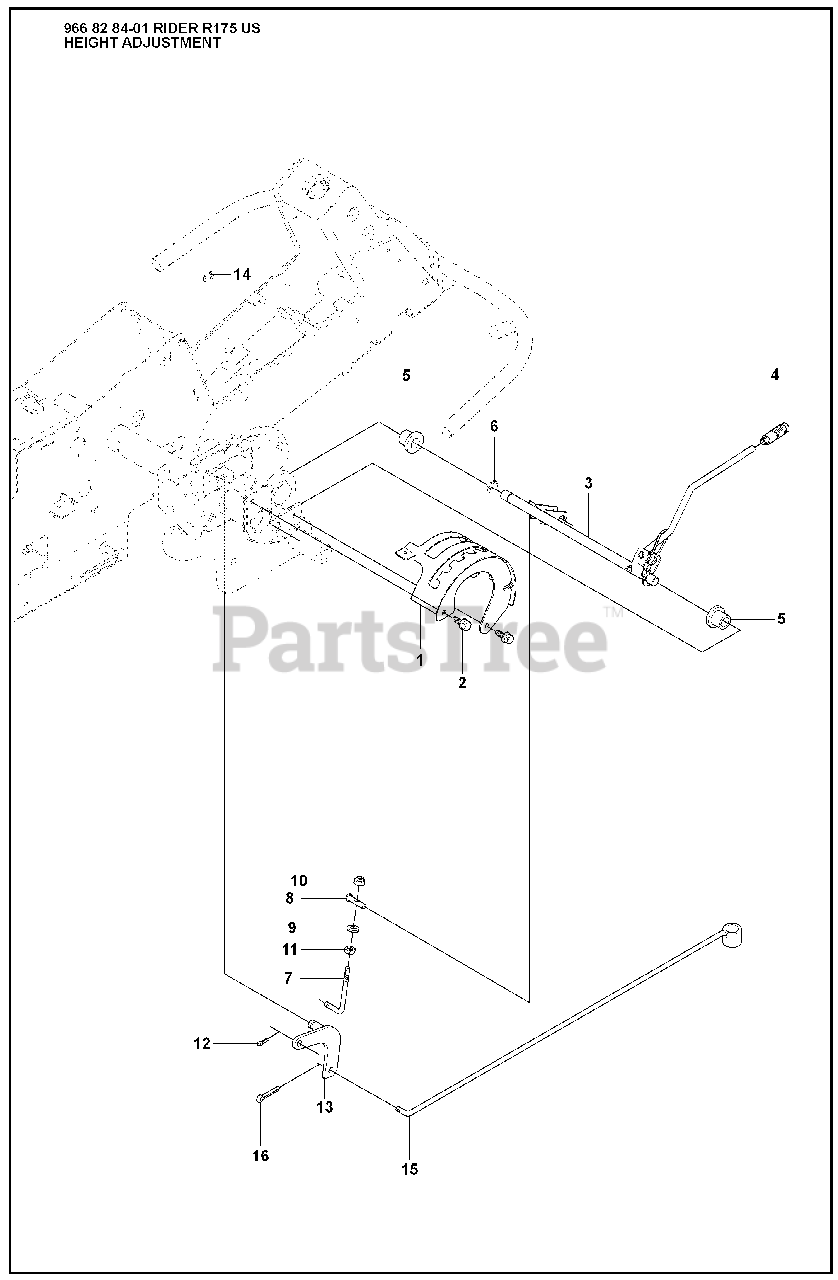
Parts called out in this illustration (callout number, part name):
1	CONTROL PLATE
3	HEIGHT ADJUSTER
4	GEAR STICK KNOB
5	BUSHING
9	WASHER
10	LOCKNUT M8
11	NUT
14	RETAINING RING
15	CLUTCH ROD
